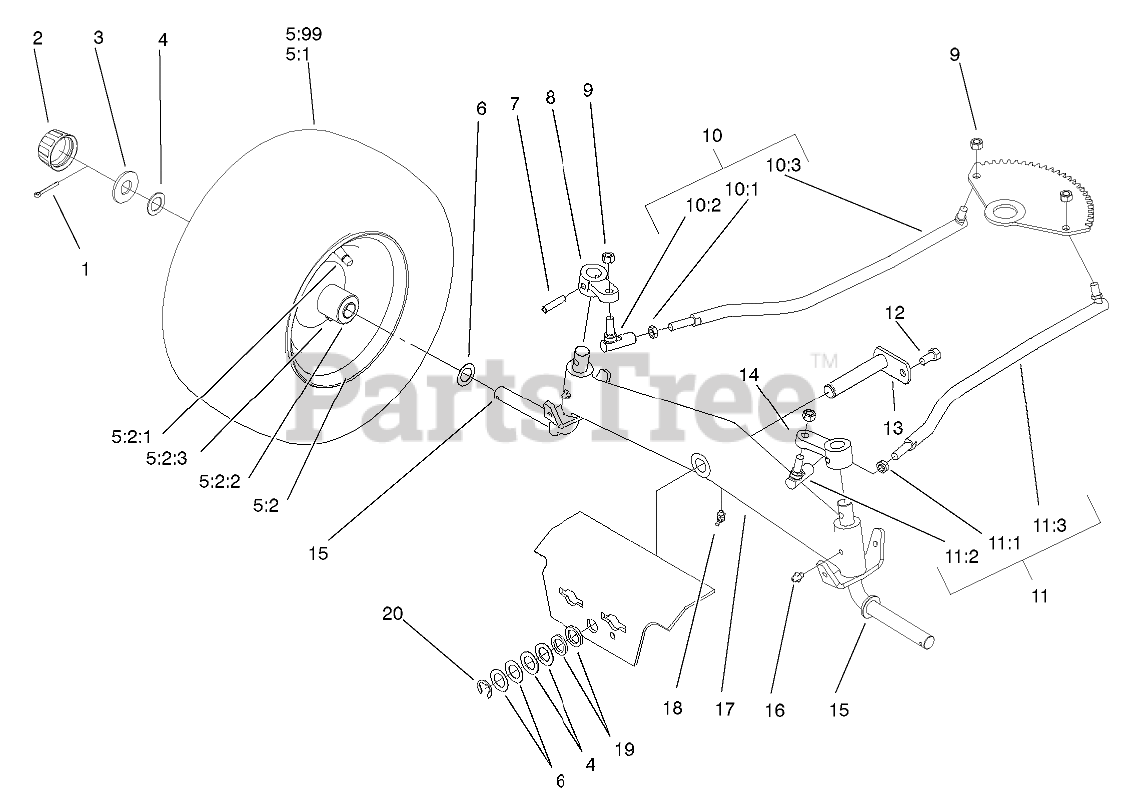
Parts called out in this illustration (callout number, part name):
1	PIN-COTTER
2	CAP-HUB
3	WASHER-PLAIN
4	WASHER
5	Front Wheel & Tire ASM
5:2	Wheel ASM
5:2:1	VALVE
5:2:2	BEARING-WHEEL
5:2:3	ZERK-GREASE
6	WASHER-SHIM
8	Arm-Front Spindle
10	LINKAGE-STEERING, RH
10:1	NUT-JAM
10:2	BALL-JOINT
10:3	Ball Link ASM
11	LINKAGE-STEERING, LH
11:1	NUT-JAM
11:2	BALL-JOINT
11:3	Ball Link ASM
12	SCREW-HWH, TAPTITE
13	PIN-AXLE
14	Arm-Front Spindle
15	SPINDLE
16	FITTING-GREASE
17	AXLE-FRONT
18	FITTING-LUBE, 45 DEG
19	Washer
20	E-RING
